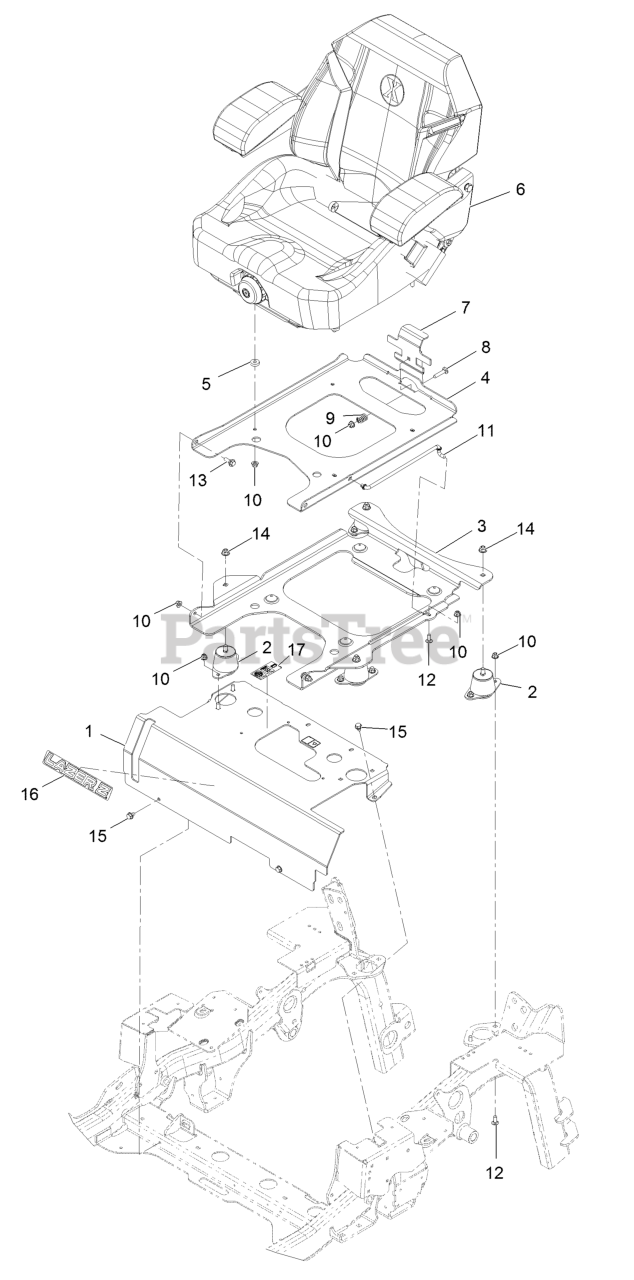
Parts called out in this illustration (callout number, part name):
1	Seat Mount ASM
2	Isolator-Seat
3	Plate-Support, Tilt Seat
4	Plate-Frame, Seat
5	Spacer-Pin, Mounting
6	ASM-Suspension Seat
7	Plate, Seat Latch
8	Bolt-Carriage 5/16-18 X 1 1/2
9	Spring-Compression
10	Nut-Nyloc 5/16-18 Flg
11	Rod-Prop
12	Bolt-Carriage 5/16-18 X 3/4 Short Neck
13	Screw-Shoulder
14	Nut-Nyloc 3/8-16 Flg
15	Screw-HWH 5/16 X 1/2 Tf
16	Decal, Lazer Model
17	Decal-Trans Fluid
